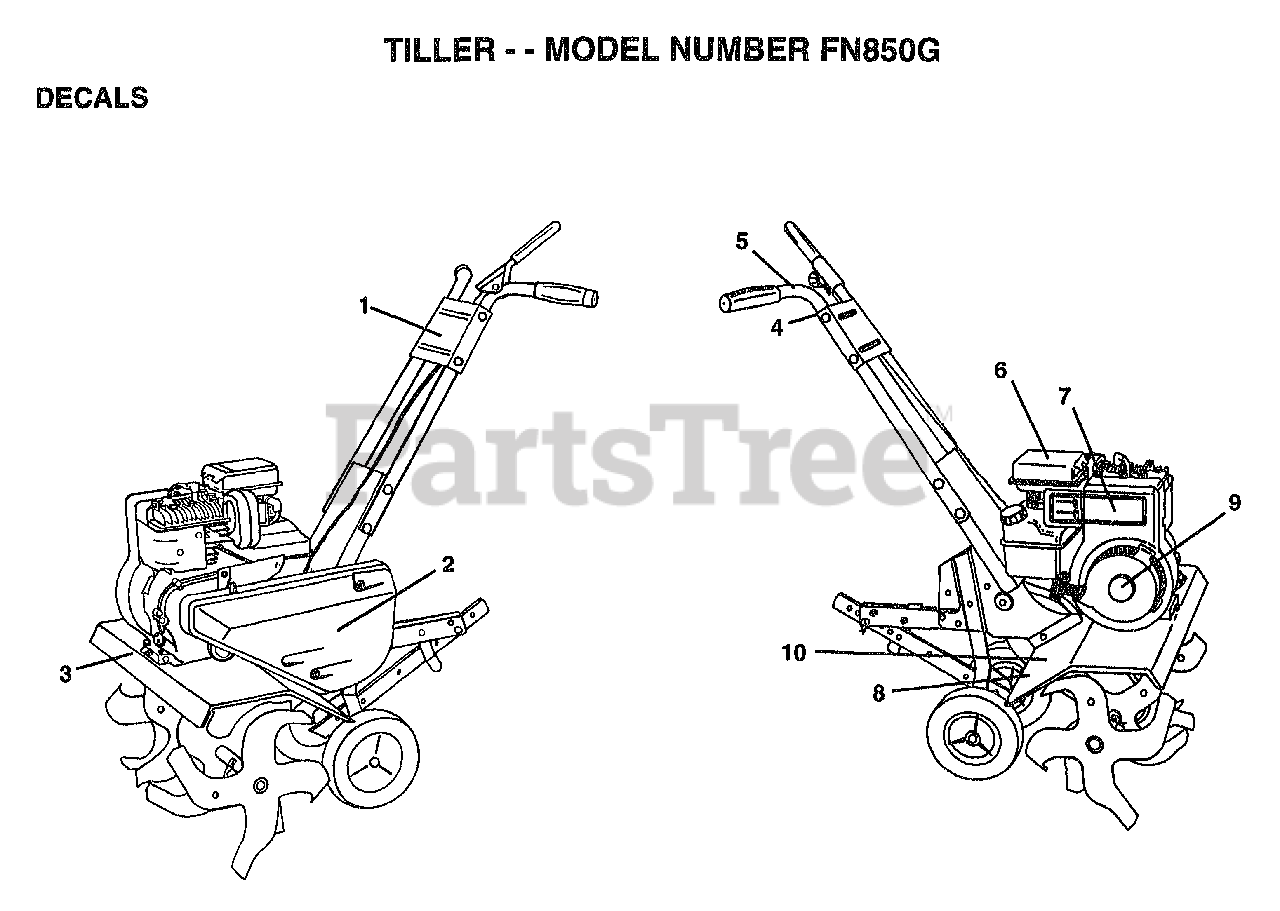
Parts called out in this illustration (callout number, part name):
1	DECAL HANDLE BRKT
2	BELT.GUARD.DECAL
3	DECAL TINE SHIELD
4	DECAL TI
5	DECAL TI
6	DECAL TI
7	DECAL, BRIGGS & STRATTON
10	DECAL.CAUTION
